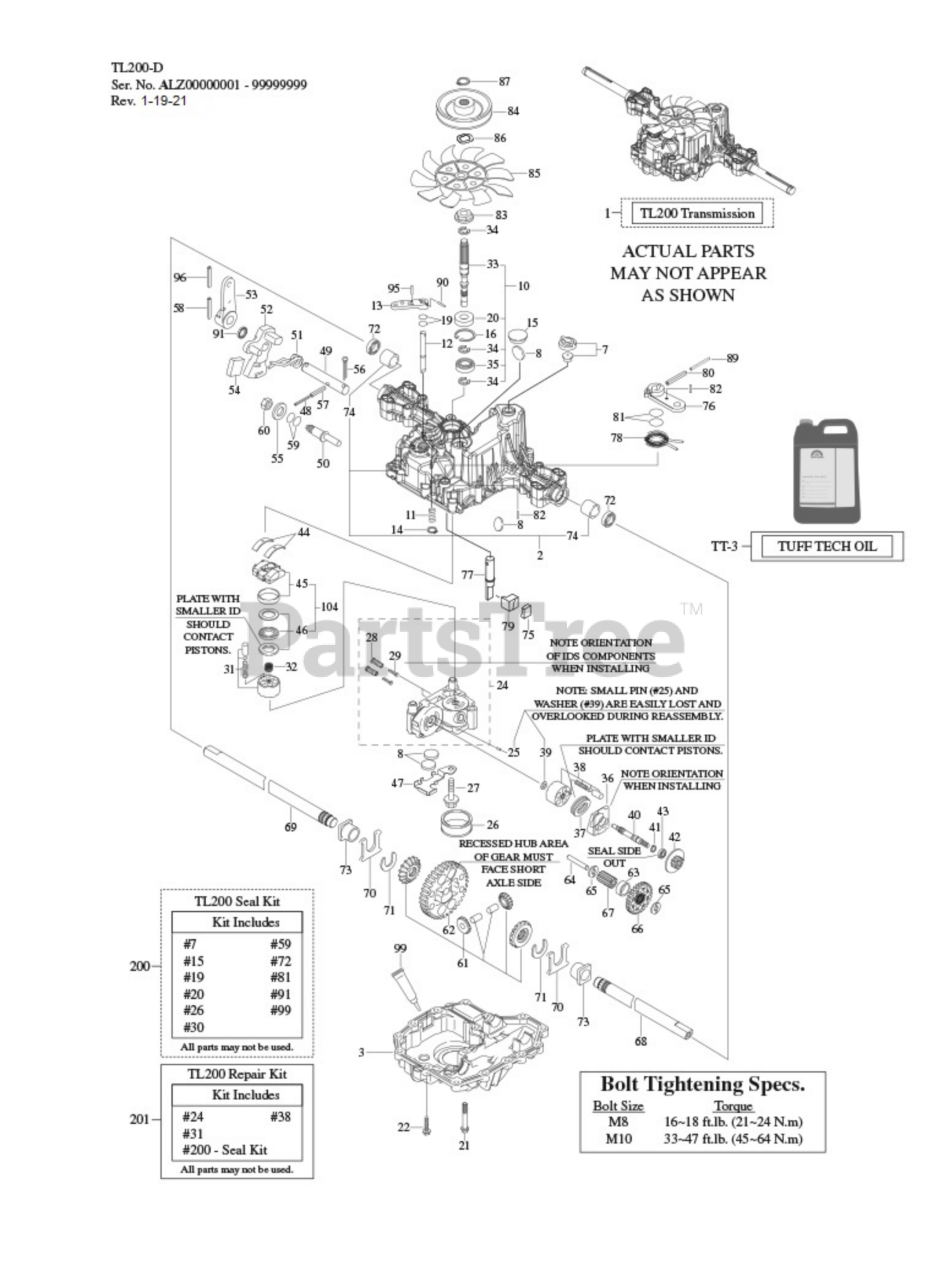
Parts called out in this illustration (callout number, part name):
1	HYDRO TRANSMISSION
2	UPPER HOUSING KIT
7	VALVE ASSEMBLY-VENT
10	PUMP SHAFT KIT (W/BRG)
21	TAP SCREWPING 8X
22	TAP SCREWPING 8X
28	VALVE-IDS 1.2
31	BLOCK KIT-PISTON &
32	SPRING-CYL BLOCK
33	SHAFT-PUMP INPUT
35	BALL BEARING
36	HOUSING-MOTOR
37	THRUST BEARING
38	BLOCK KIT-PISTON &
44	BEARING-CRADLE THRUST
47	HOLDER-MAGNET
49	SHAFT-CONTROL
51	TORSION SPRING
52	ARM-CONTROL A
53	LEVER-CONTROL F
55	FLAT WASHER 12
56	COTTER PIN 1/8 x .75
57	SPRING PIN 6 x 3
58	ROLL PIN 6 x 4
61	DIFFERENTIAL GEAR ASSEMBLY
62	FINAL GEAR 54T
63	COLLAR-FINAL PINION
64	SHAFT-REDUCTION
65	THRUST WASHER
66	GEAR-REDUCTION 37T
67	FINAL PINION GEAR 10T
68	AXLE SHAFT (LH)
69	AXLE SHAFT (RH)
70	THRUST WASHER
73	BUSHING-FLG AXL
78	SPRING-BRAKE RETUR
79	ACTUATOR-BRAKE
80	SPRING PIN 5 x 3
82	SPRING PIN 4 x 1
83	COLLAR-SPLINE
85	HYDRO FAN BLK
89	SPRING PIN 3 x 32
90	SPRING PIN 3 x 2
95	SPRING PIN 3 x 1
96	ROLL PIN 3.5 x 4
104	SWASH PLATE KIT
TT-3	TUFF TECH OIL 3 LITER BOTTLE
